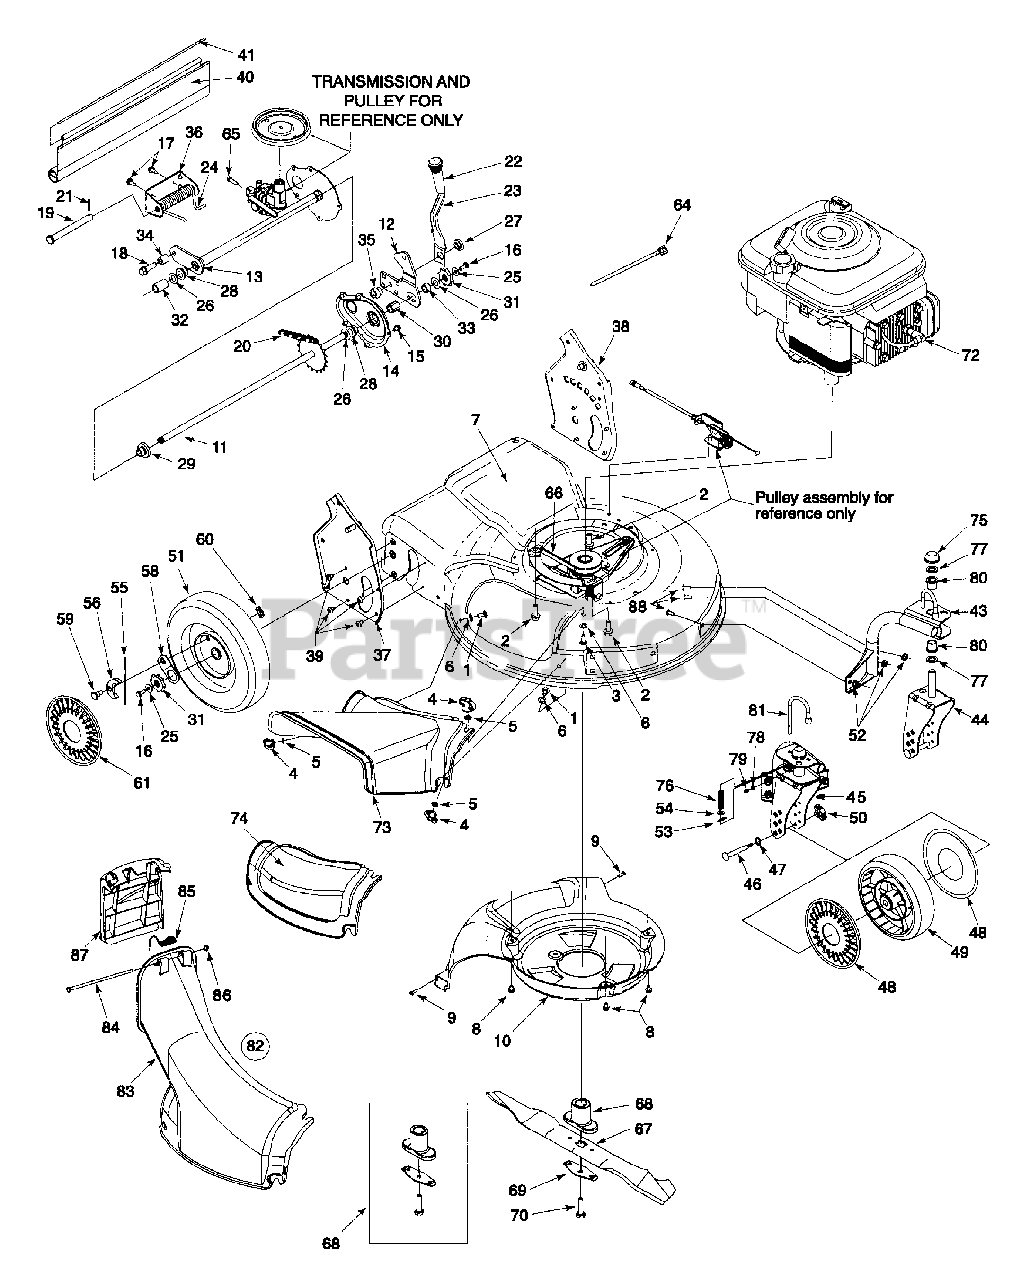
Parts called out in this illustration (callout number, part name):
1	Scr. Carr. 1/4-20 x .62
2	Scr. TT:3/8-18:1.00
3	Scr. 1/4-20 x .750
4	Wing Nut 1/4-20
5	Nut, Push.25 I.D. x .50 O.D.
6	Wash. Fl. .334 I.D.x.62 x.03
7	Deck-21"
8	Scr. TT 1/4-20 x .375
9	Scr. HL. 1/2-14 x .750
10	Baffle
11	Rear Axle Assembly
12	Pivot Arm Assembly
16	Cap Screw HH 1/4-20 x .620
17	Scr. AB 1/4-14 x .825
18	Scr. 3/8 116 x .25
19	Clevis Pin .50 Dia. x 4.82 Lg.
20	Chain-Endls. #48 .500P x 24L
21	Cotter Pin .1250. D. x .75
23	Spring Lever
24	Torsion Spring
25	Bell Wash. .285 x .75 x .082
26	Fl. Wash 508 I.D. 1.000 x.020
27	Nut Shld. .825 Dia. x .165 Lg.
28	Hx.Flg. Brg 506 I.D. x .590 L.
29	Hx.Flg. Brg. .506 I.D. x.715 L.
30	Hx. Slv. Brg 504 I.D. x .830 L.
31	Wheel Rachet
32	Spa. .550 I.D. x /750 O.D.
33	Spa. .51 .D. x .70 O.D. x 38 L.
34	Spa. .385 x .624 x .700
35	Shld. Spa. .385 I.D. X .715 Lg.
38	Handle Brkt. Ass'y. L.H.
39	Scr. AB 1/4-14 x .500
40	Trail Shield
41	Trail Shield Wire
43	Caster Assembly L.H.
43	Caster Assembly R.H.
44	Caster Bracket Assembly: RH
45	Caster Bracket Assembly: LH
46	Caster Axle .374 Dia x 2.50"
47	Wave Washer
48	Hub Cap, Gray w/ hole
49	Wheel 7 x 2 Gray
50	Wing Nut 1/4-20
51	Wheel 9 x 2 Gray, Slv.
52	Lock Nut 5/15-18
53	Cotter Pin .072 x .12 Lg.
54	Fl. Wash. .330 x .830 x .060
55	Spring, Ratchet, Plastic
56	Pawl- R.H.
56	Pawl - L.H.
58	Ratchet Pawl Plate
59	Scr. Shld. .340 x .285
60	Top Lock Tab Weld Nut 1/
61	Hubcap -Gray
64	Cable Tie
65	Hex Scr. 5/16-18
66	Belt
67	21" Mulching Blade
68	Blade Adapter Kit
69	Blade Bell Suport
70	Hex Bolt 3/8-24x2.5" Lg.
72	Spark Plug Insulator
73	Side Discharge Chute
74	Mulch Cover
75	Push Cap
76	Compression Spring
77	Fl. Wash. .5/8 I.D. x 1" O.D.
78	Fl. Wash. .203 x .403 x .
79	Fitting - Grease
80	Flange Bearing
81	Locking Pin
82	Chute Ass'y
83	Discharge Chute
84	Pivot Rod
85	Torsion Spring
86	Push Cap
87	Chute Door
88	Carr. Bolt 5/16-18 x.62
